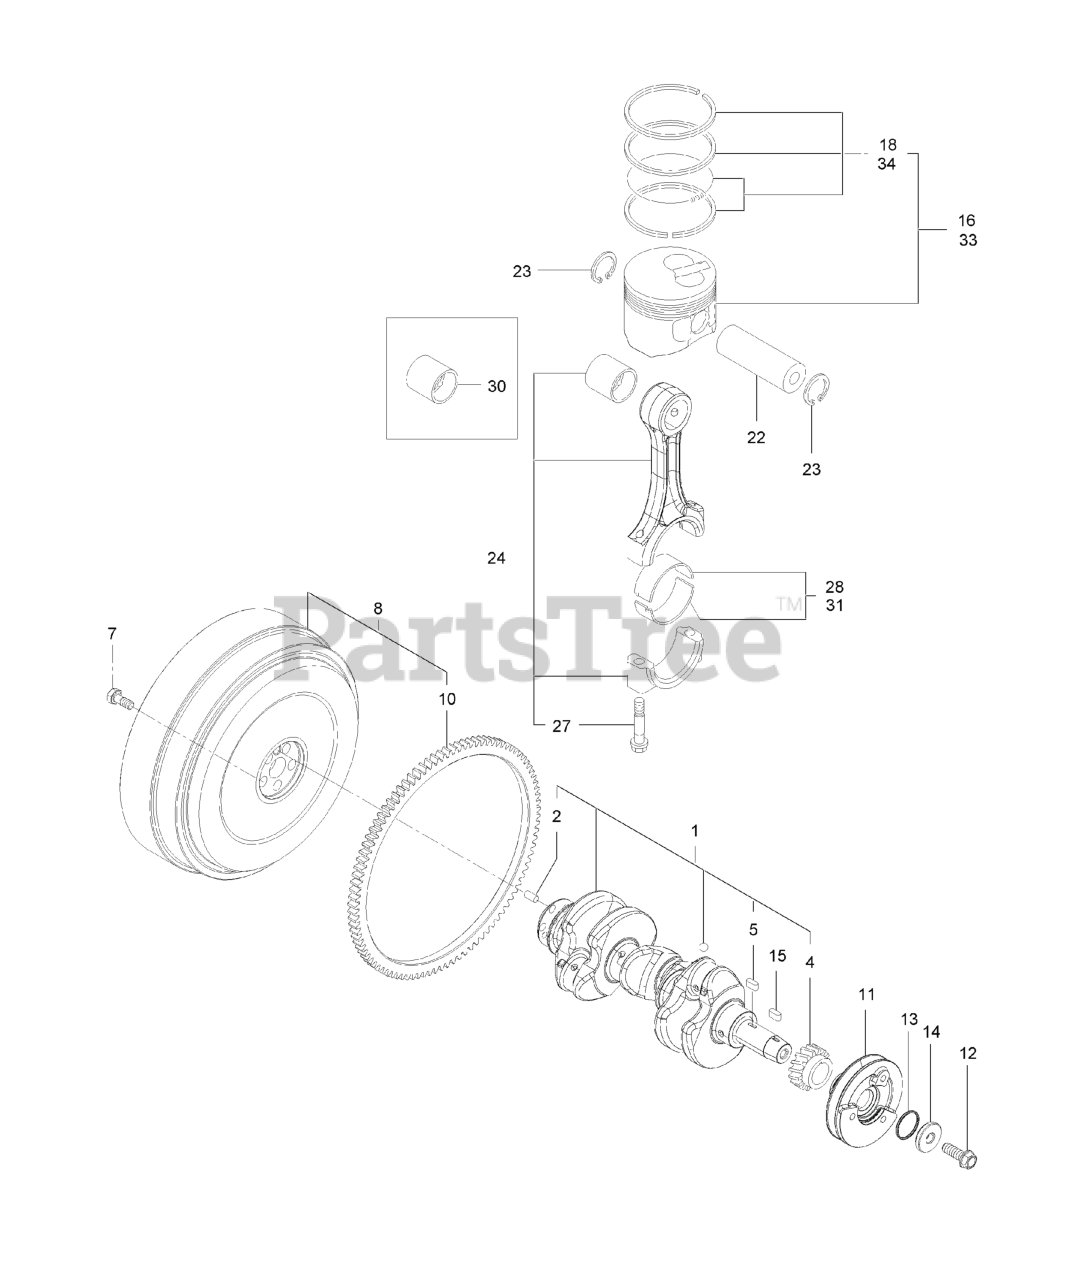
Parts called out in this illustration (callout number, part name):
1	CRANKSHAFT ASM
4	GEAR-CRANKSHAFT
7	BOLT, FLYWHEEL 5
8	FLYWHEEL ASM
10	GEAR-RING
11	V-PULLEY, CRANKSHAFT 1
12	BOLT, FLANGE 12X1.25 1
13	GASKET-WASHER
16	PISTON ASM
18	RING ASM
22	PIN-PISTON
24	ROD ASM-CONNECTING
27	BOLT-CONNECTING ROD
28	BEARING-CRANK PIN
30	BEARING-PISTON PIN
31	BEARING, PIN 0.25
33	PISTON ASM
34	RING ASM
